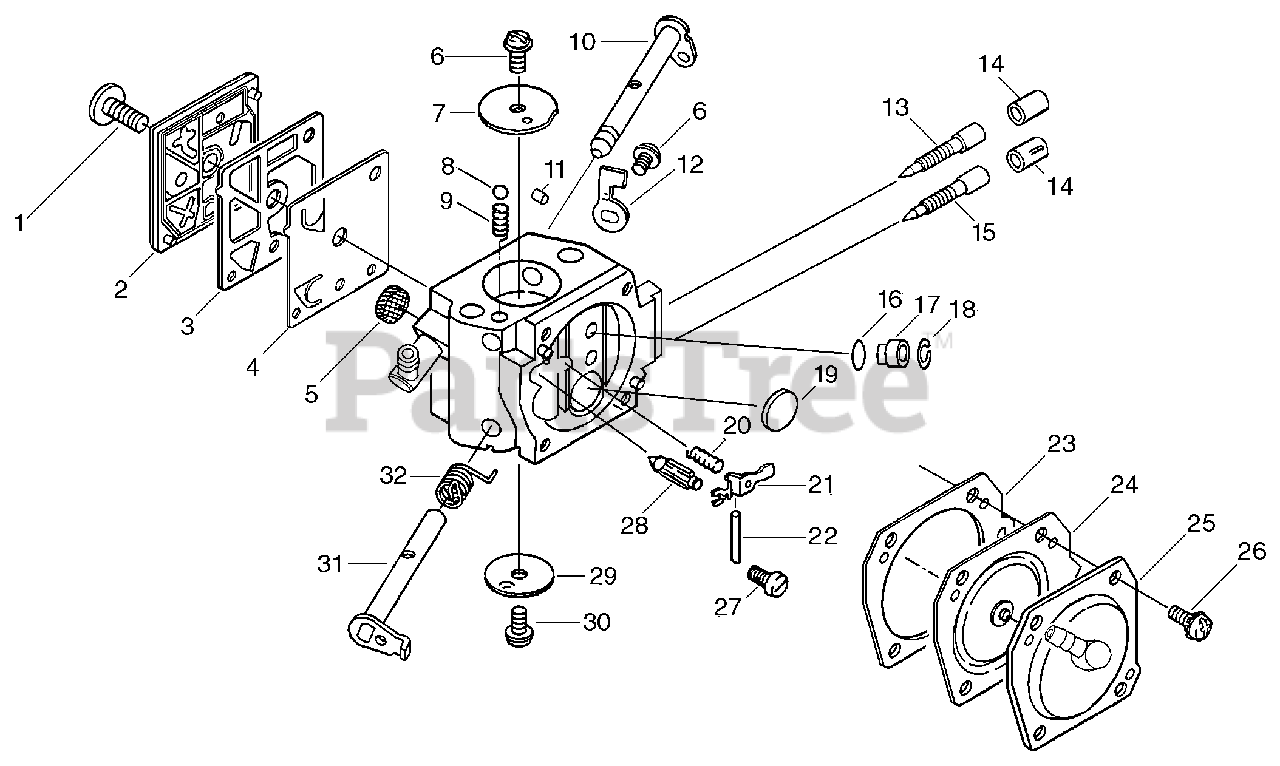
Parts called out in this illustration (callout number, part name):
1	SCREW, PUMP COVER
2	COVER, PUMP
3	GASKET, PUMP
4	DIAPHRAGM, PUMP
5	STRAINER
7	VALVE, CHOKE
8	BALL, CHOKE
10	LEVER, CHOKE
12	STOP, THROTTLE
13	NEEDLE - HIGH SPEED
14	CAP, LIMITER
15	NEEDLE - MIXTURE
16	O-RING
17	JET, MAIN - 42
18	RING, RETAINING
19	PLUG, WELCH
20	SPRING, METERING LEVER
21	LEVER, METERING
22	PIN, METERING LEVER
23	GASKET, METERING
24	DIAPHRAGM, METERING
25	COVER, METERING
27	SCREW, METERING LEVER PIN
28	VALVE, INLET NEEDLE
29	VALVE, THROTTLE
31	SHAFT, THROTTLE
32	SPRING, THROTTLE RETURN
